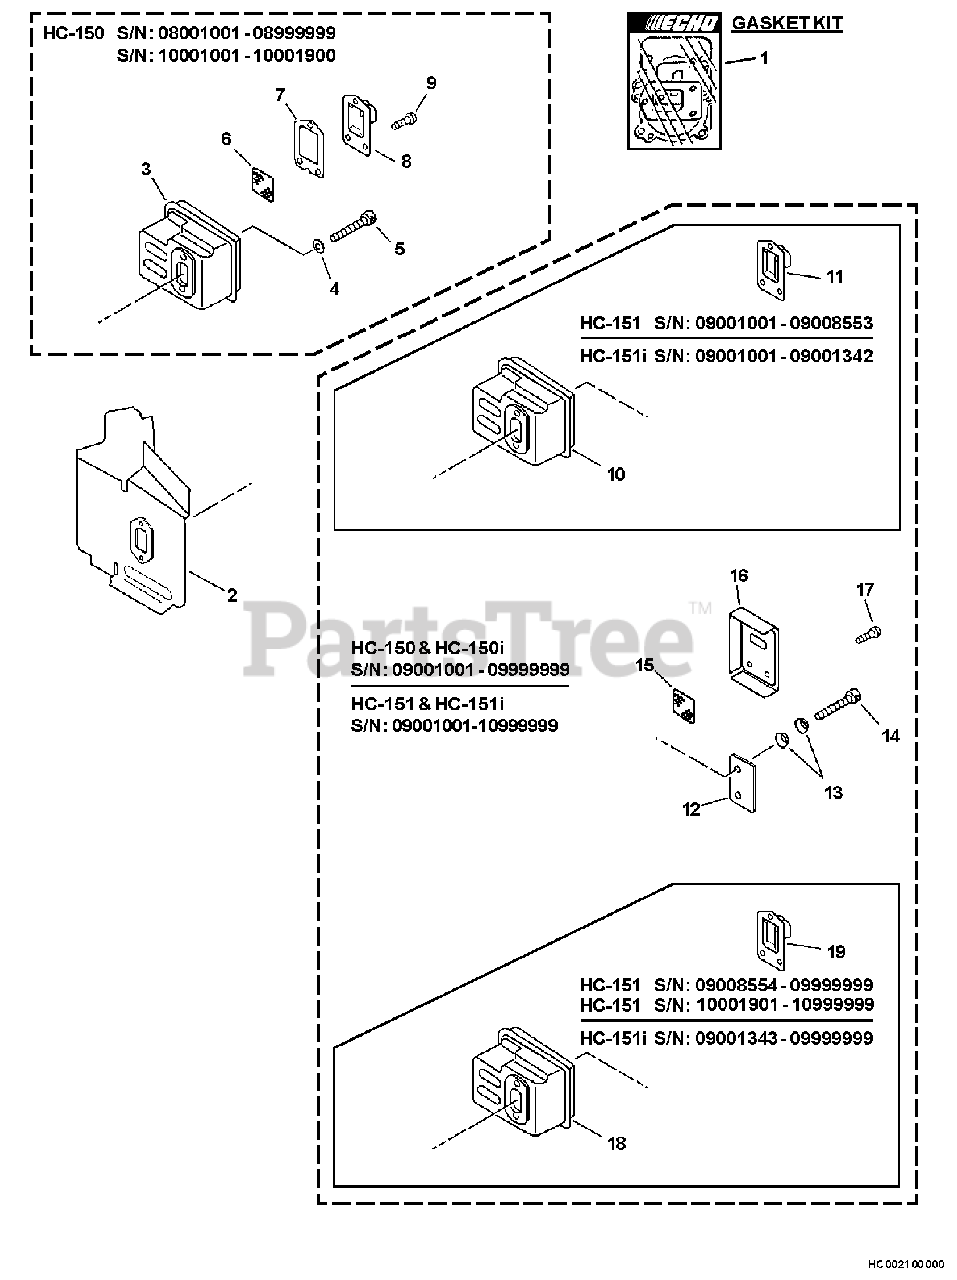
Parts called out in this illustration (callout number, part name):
1	GASKET KIT
2	SHIELD, EXHAUST
4	WASHER - 5
5	SCREW - 5X50
6	SCREEN, SPARK ARRESTOR
7	GASKET, EXHAUST
8	GUIDE, EXHAUST
9	SCREW - 4X10
10	MUFFLER
11	GUIDE, EXHAUST
13	WASHER - CONICAL
14	SCREW - 5X55
15	SCREEN, SPARK ARRESTOR
16	GASKET, EXHAUST
17	SCREW - 4X12
18	MUFFLER
19	GUIDE, EXHAUST
